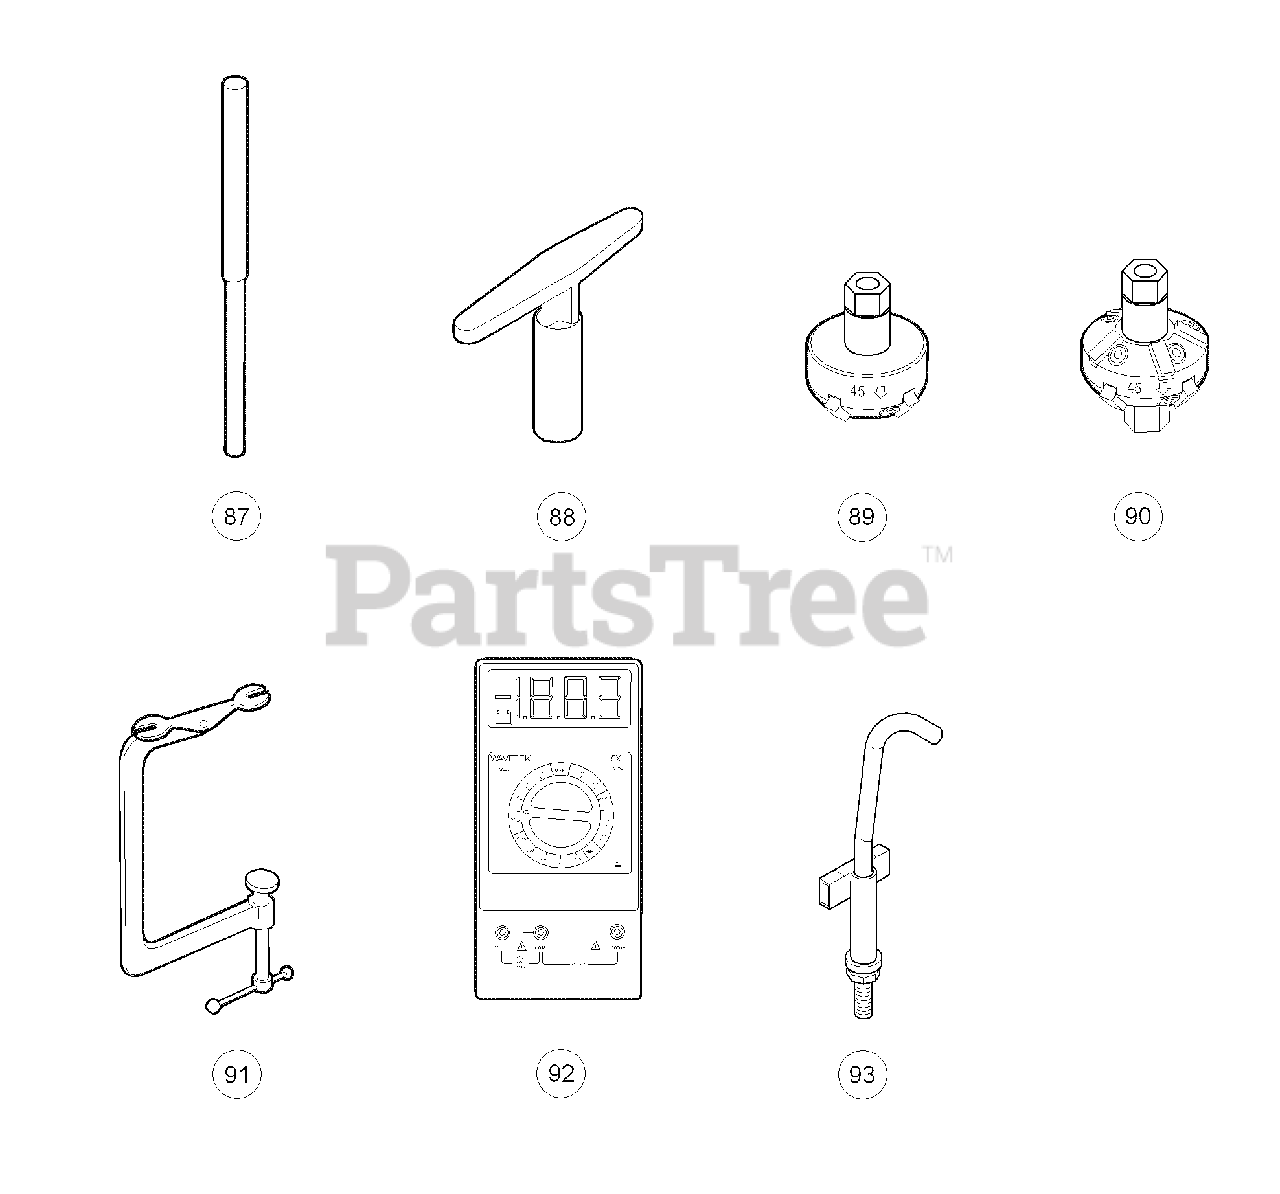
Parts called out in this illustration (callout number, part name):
86	Valve Seat Cutter Guide
87	Valve Seat Cutter T-Wrench
88	Valve Seat Cutter, 45°
89	Valve Seat Cutter, 45°/30°
90	Valve Spring Compressor
91	Volt Ohm Meter
92	Tool, Tensioning, Starter Generator
